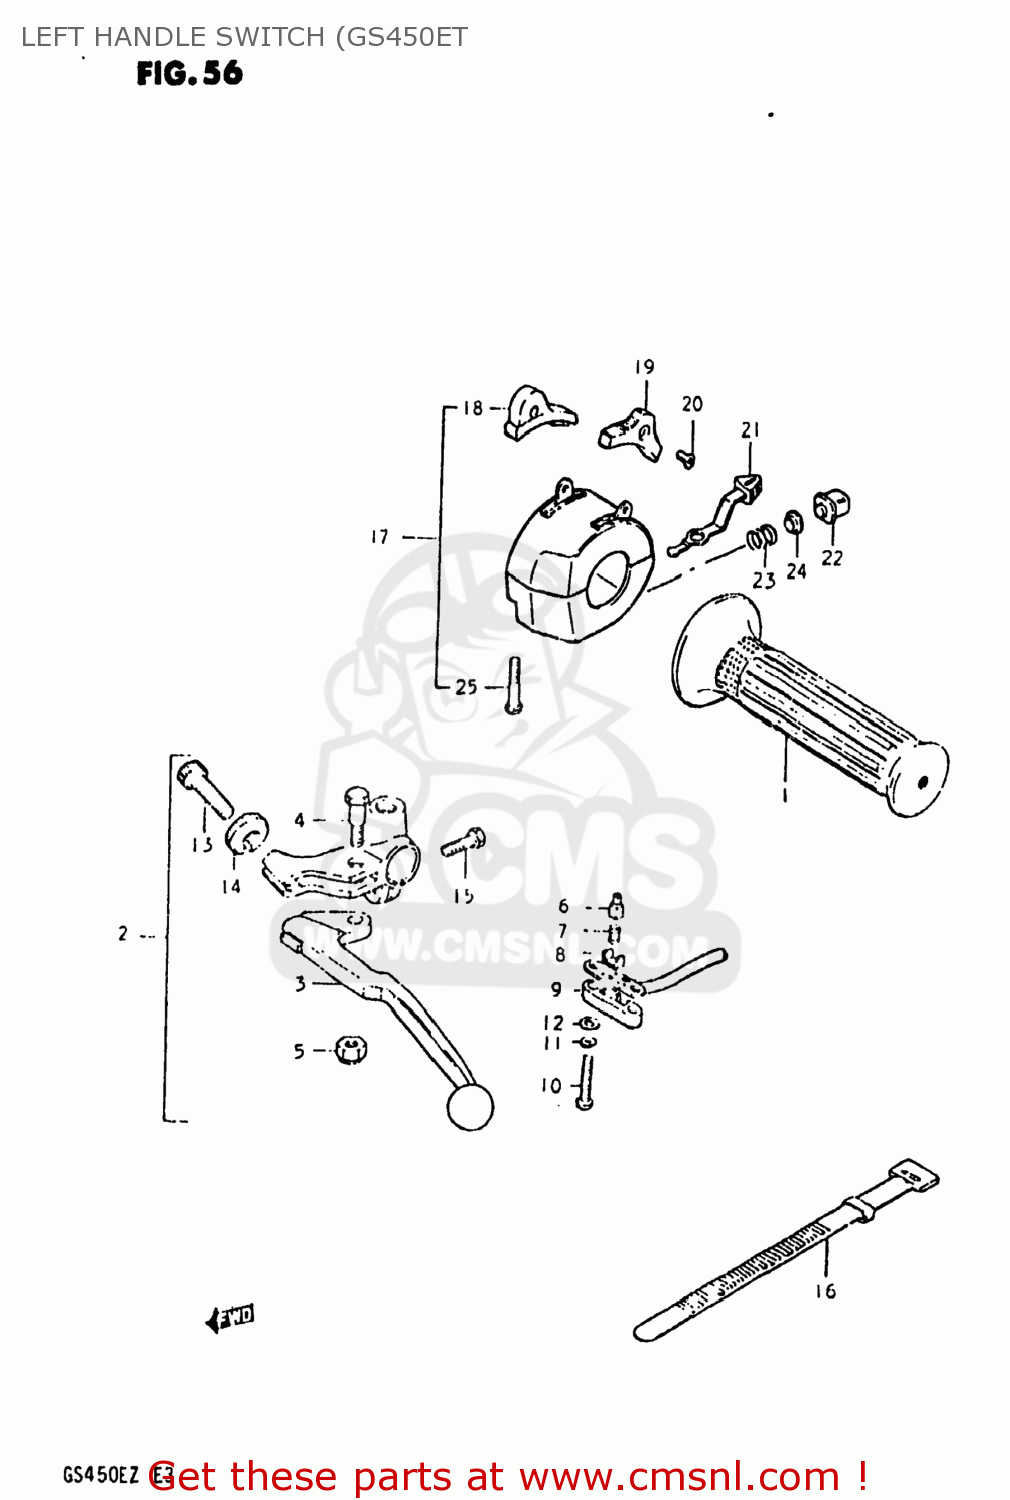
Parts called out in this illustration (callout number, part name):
1	GRIP,LEFT
2	LEVER ASSEMBLY
3	LEVER,CLUTCH
4	BOLT,LEVER
5	NUT 6MM
6	HOLDER
7	SPRING
8	PLATE
9	COVER,FR BK TERMINAL BASE
10	SCREW
11	LOCK WASHER
12	WASHER
13	ADJUSTER,CABLE
14	NUT,CABLE ADJUSTER
15	BOLT,CLUTCH LEVER HOLDER
16	CLAMP(L:120)
17	SWITCH ASSY,HANDLE,L
18	KNOB,STOP
19	KNOB,DIMMER SWITCH
20	SCREW
21	KNOB,TURNSIGNAL
22	BUTTON,HORN
23	SPRING
24	CONTACT
25	SCREW
